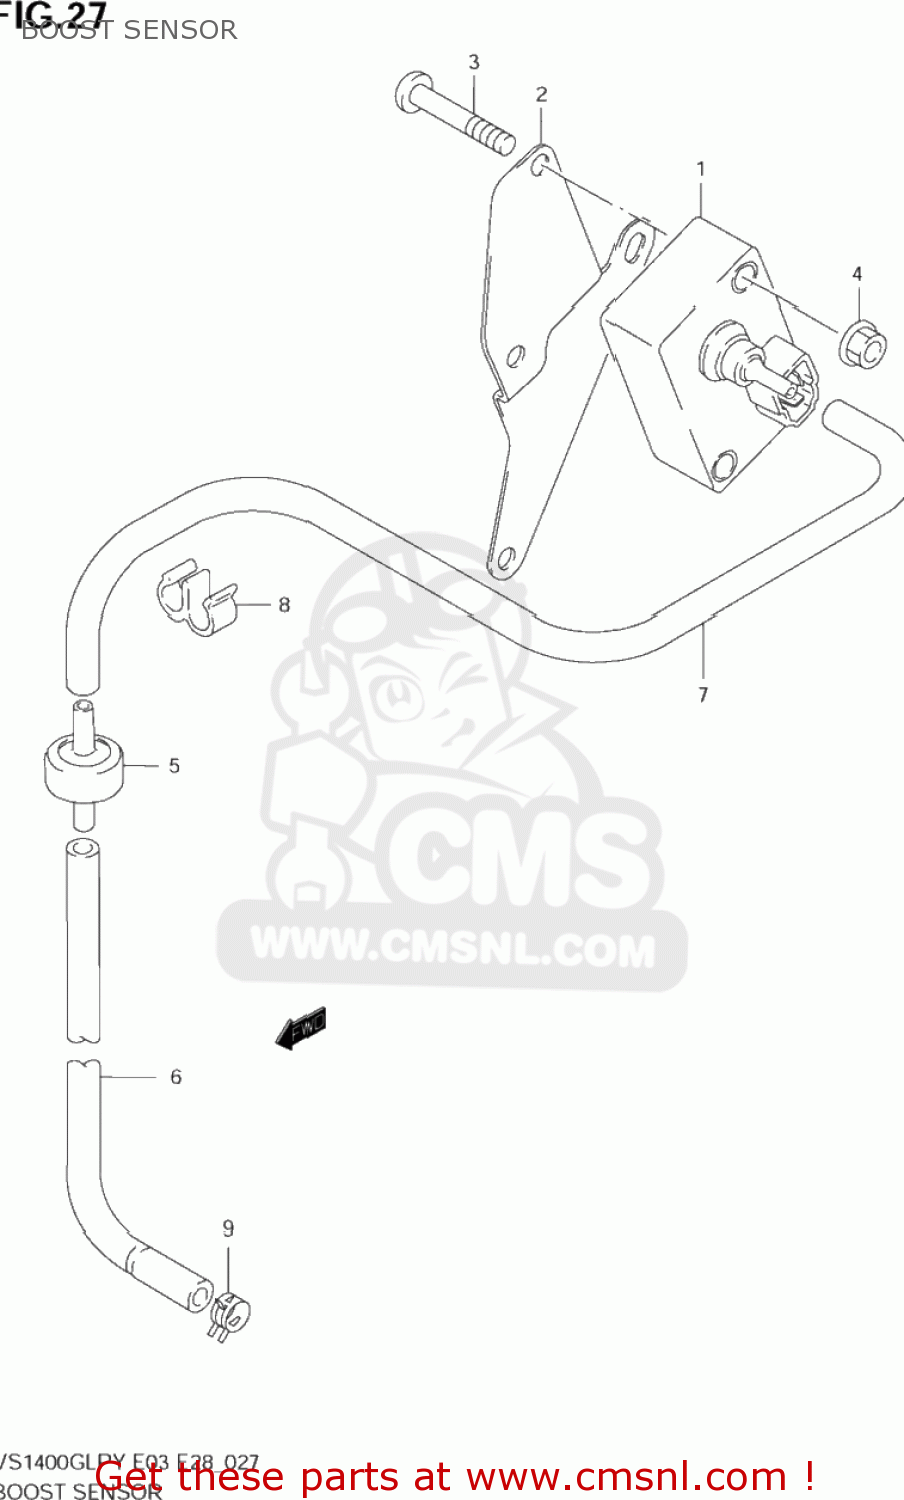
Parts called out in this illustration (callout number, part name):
1	SENSOR ASSY,BOOST
2	BRACKET,BOOST SENSOR
3	SCREW 6X30
4	NUT
5	FILTER,VSV
6	HOSE,BOOST NO.1
7	HOSE(3.5X7.5X2000)
8	CLAMP
9	CLIP
